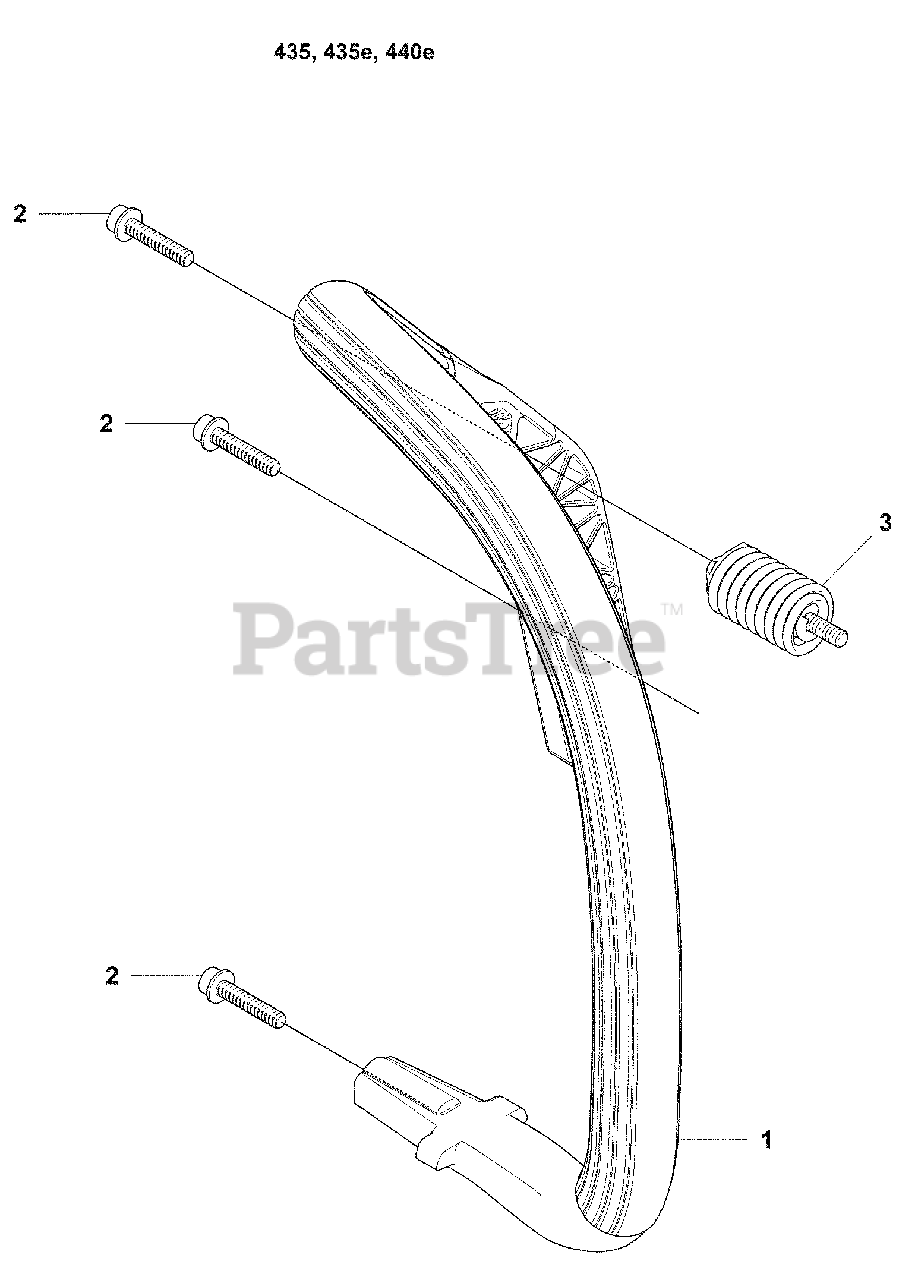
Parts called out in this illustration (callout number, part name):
1	Front Handle
2	Screw, 3 X 25 IHSCFT
3	Insulator
